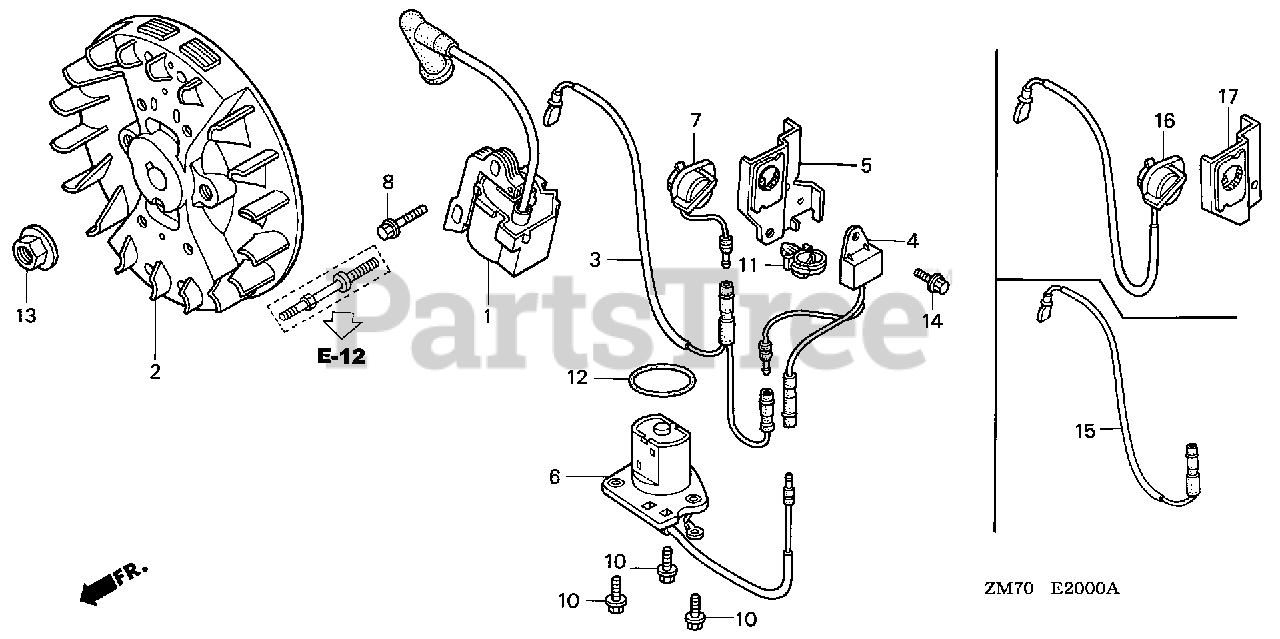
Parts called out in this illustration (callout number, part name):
1	COIL ASSY., IGNITION
3	WIRE, STOP SWITCH
4	ALERT UNIT, OIL
5	BRACKET, STOP SWITCH
6	SWITCH ASSY., OIL LEVEL
7	SWITCH ASSY., ENGINE STOP
8	BOLT, FLANGE (5X20)
10	BOLT, FLANGE (5X14)
11	CLIP, HARNESS
12	O-RING (34.6X2.5)
13	NUT, FLANGE (10MM)
14	BOLT, FLANGE (6X8)
